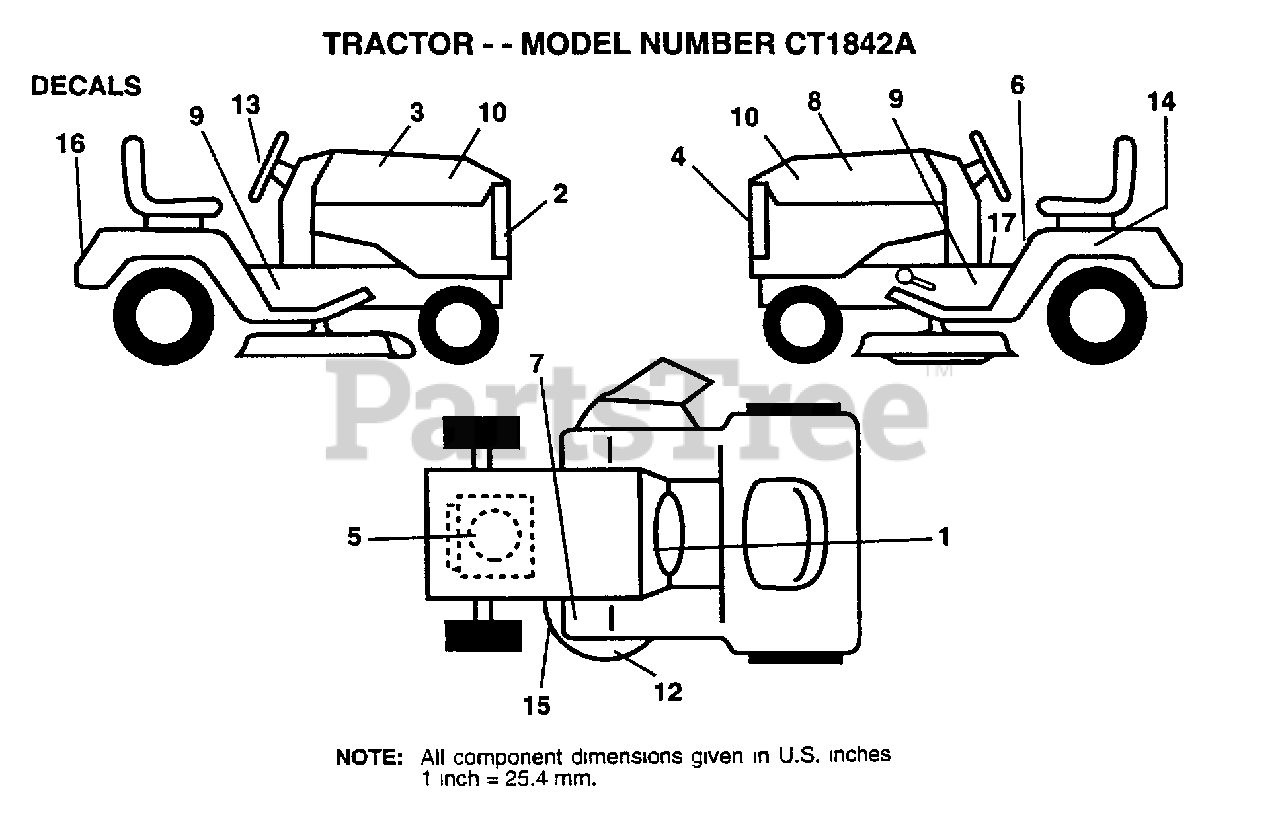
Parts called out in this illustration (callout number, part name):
1	DECAL.DASH.INST.
2	GRILL DECAL
3	DECAL HOOD RH RLY
5	DECAL B&S 18 HP OPLLN/IC
6	DECAL
8	DECAL HOOD LH RLY
9	CHASSIS DECAL
10	DECAL.HOOD.INSERT
13	DECAL.WHL.STRG.RY
14	DECAL.BATRY.3-3908
15	DECAL
16	FENDER DECAL
17	DECAL BRAK PARK
